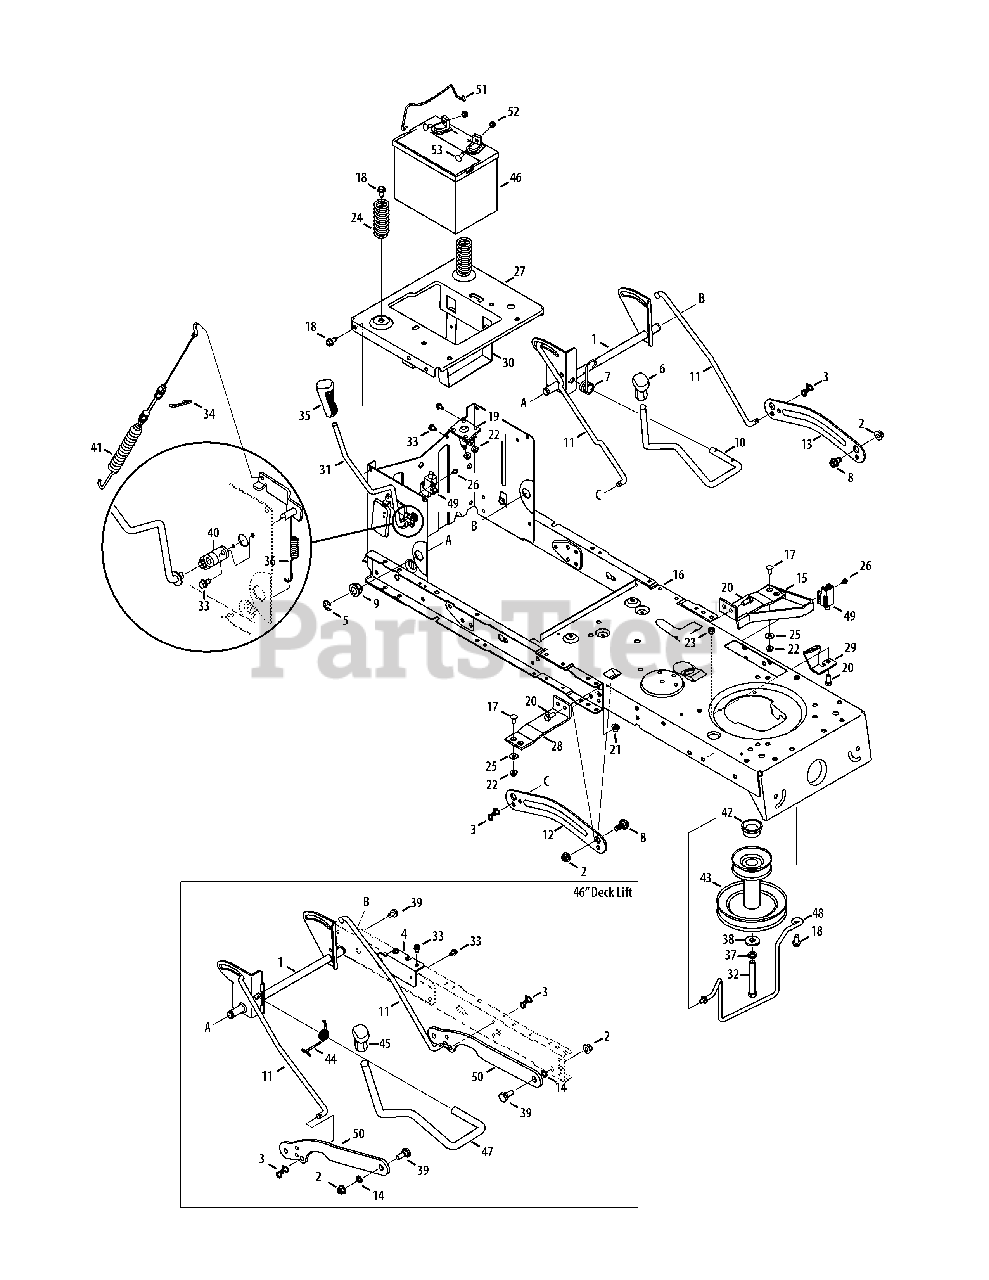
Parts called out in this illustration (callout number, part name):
1	Shaft Assembly Lift 42" Deck
1	Shaft Assembly Lift 46" Deck
2	Nut, Flange Lock, 3/8-16, GrF
3	Pin, Cotter, Bow Tie
4	Frame Brace Bracket
5	Ring, E-Type, .625 Dia.
6	Grip, Handle, 1/2
7	Spring, Torsion 42" Deck
8	Screw, Shoulder, .625 x .175, 3/8-16
9	Bearing, Hex Flange
10	Deck Handle, Lift, 42" Deck
11	Rod, Lift
12	Lift Arm, Deck - RH Powder Black
12	Lift Arm, Deck - RH Black Jack
13	Lift Arm, Deck - LH Powder Black
13	Lift Arm, Deck - LH Black Jack
14	Washer, Flat, .385 x .62 x .063
15	Support Bracket Assembly Powder Black
15	Support Bracket Assembly Black Jack
16	Frame Assembly Powder Black
16	Frame Assembly Black Jack
17	Carriage Screw, 1/4-20 x .62
18	Screw, 5/16-18, .750
19	Solenoid
20	Hex Screw, 5/16-18 x .75
21	Flange Lock Nut, 5/16-18
22	Nut, Flange Lock, 1/4-20, GrF
23	Hex Lock Nut, 5/16-18
24	Spring, Compr. , 1.28 OD x 3.125
25	Flat Washer, .28 x .74 x .063
26	Shoulder Screw, #10-32 x .500
27	Seat Bracket, Frame Powder Black
27	Seat Bracket, Frame Black Jack
28	Bracket, Runing Board
29	Frame Support Bracket Powder Black
29	Frame Support Bracket Black Jack
30	Bracket, Battery
32	Screw, 7/16-20, 3.25 42" Deck
33	Screw, 1/4-20, 0.500
34	Pin, Click, .092 x 1.64
35	Grip, Handle, 3/8
36	Spring, Extension
37	Washer, Lock, 7/16
38	Washer, Flat, .450 x 1.250 x .164
39	Bolt, Shldr. .500 x .270 3/8-16
40	Bearing, PTO
41	Cable, Deck Engagement
42	Spacer, 1.010 x 1.400 x .825, 42" Deck
43	Engine Pulley
44	Spring, Torsion 46" Deck
45	Grip, Handle, 5/8
46	Battery, 155 CCA
47	Deck Handle, Lift, 46" Deck
48	Rod, Belt Keeper (42" Deck)
48	Rod, Belt Keeper (46" Deck)
49	Switch, Interlock
51	Battery Hold Down Rod
52	Nut, Sems, 1/4-20
53	Screw, Carriage, 1/4-20, .75, Gr5
